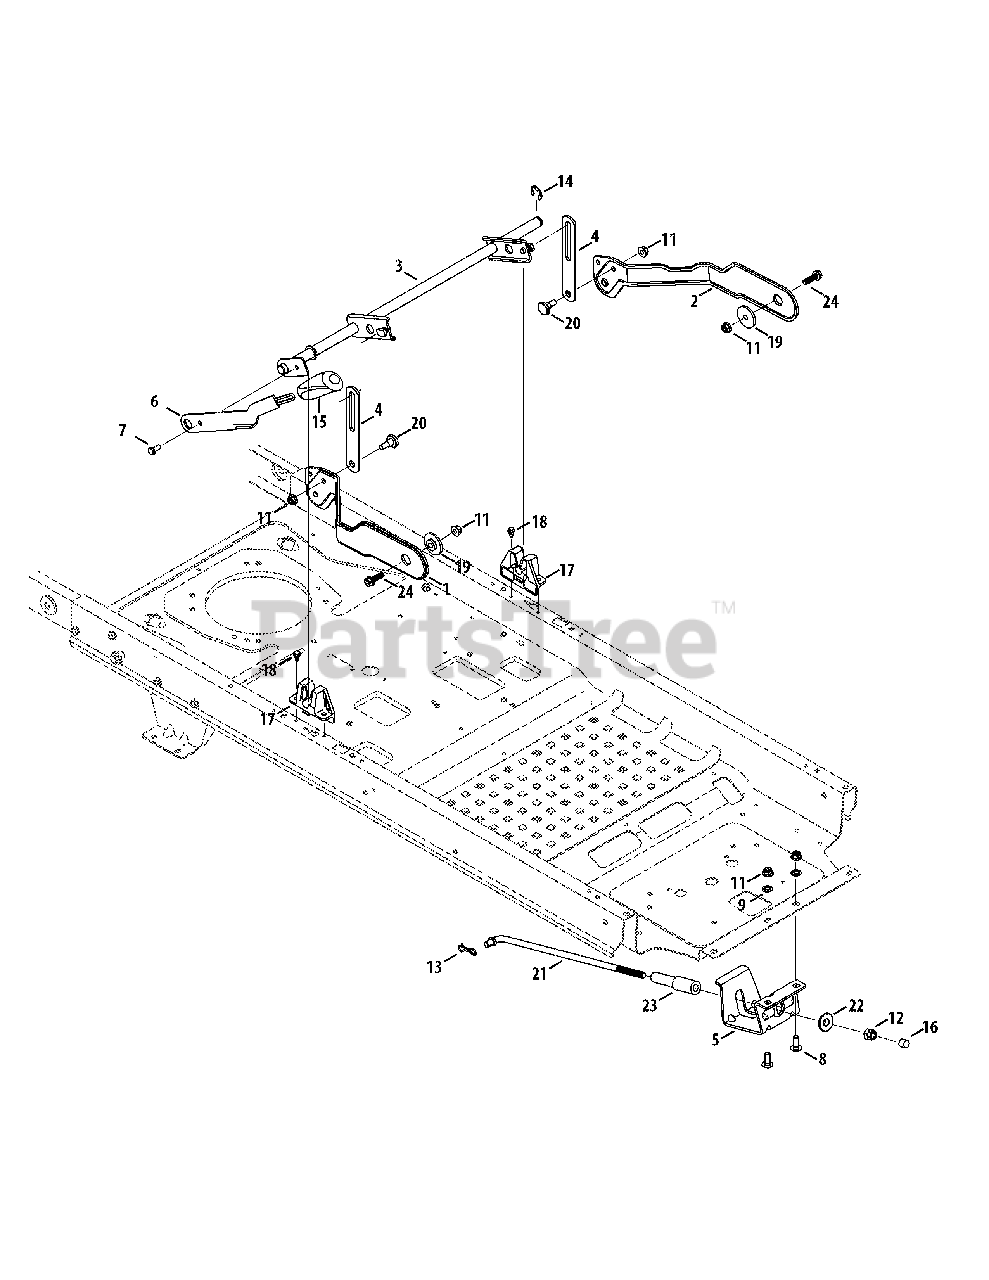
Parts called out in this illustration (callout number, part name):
1	RH Deck Lift Bracket Assembly
2	LH Deck Lift Bracket Assembly
3	Deck Lift Shaft Assembly
4	Lift Link Plate
5	Support Rod Mount Bracket
6	Deck Lift Handle
7	Hex Screw, 5/16-18 x .75
8	Carriage Bolt, 3/8-16 x 1.00
9	Push Nut, 3/8
10	Flange Lock Nut, 5/16-18
11	Flange Lock Nut, 3/8-16
12	Hex Nut, 1/2-13
13	Cotter Pin
14	E-Ring, .750
16	End Cap
17	Deck Lift Bracket
18	Shoulder Screw, 1/4-20 x .50
19	Anti-Rotate Shoulder Spacer
20	Shoulder Screw, .500 x .434
21	Front Deck Lift Rod
22	Deck Lift Pivot Cup
23	Nylon Sleeve, .55 x 4.50
24	Hex Washer Screw, 3/8-16 x 1.000
